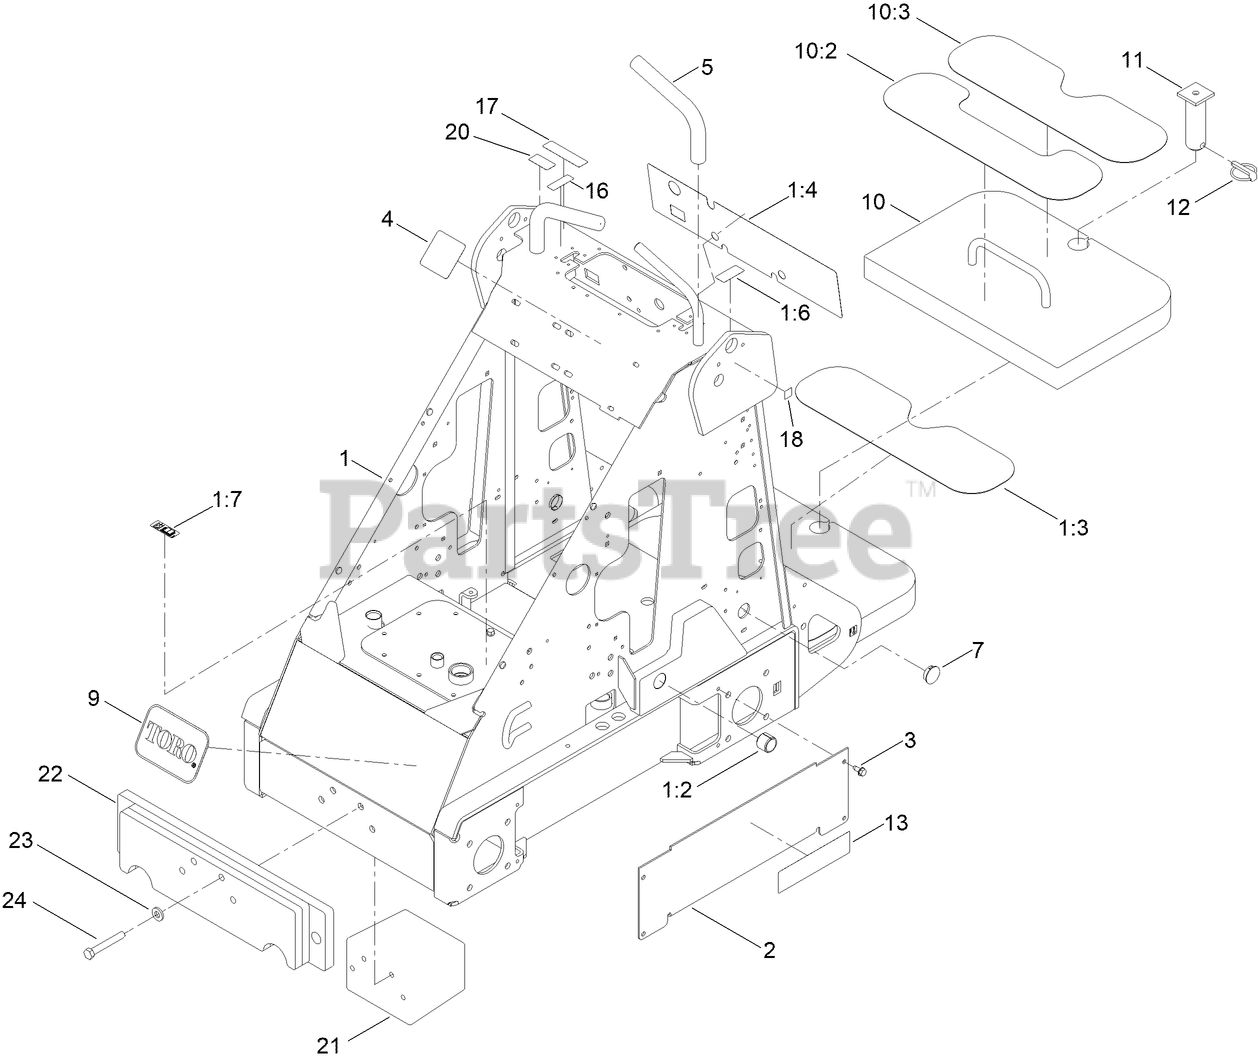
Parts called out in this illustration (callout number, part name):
1	FRAME ASM
1:2	BUSHING-TENSION
1:3	TREAD-FOOT
1:4	DECAL-CONTROL PANEL
1:6	DECAL-THROTTLE
1:7	DECAL-OIL, HYD
2	COVER-HOSE
3	SCREW-HWHTF
4	DECAL-SELECTOR, SPEED
5	GRIP-CUSHION
7	PLUG-HOLE
9	DECAL
10	COUNTERWEIGHT ASM
10:2	TREAD-FOOT
12	PIN-LYNCH
16	DECAL-CHOKE
17	DECAL-ARRESTOR, SPARK
18	DECAL-POINT, LIFT
20	DECAL-PROTECTION, EAR
21	WEIGHT-FRONT, COUNTER
22	WEIGHT-COUNTER [BLACK]
23	WASHER
24	SCREW-HH
